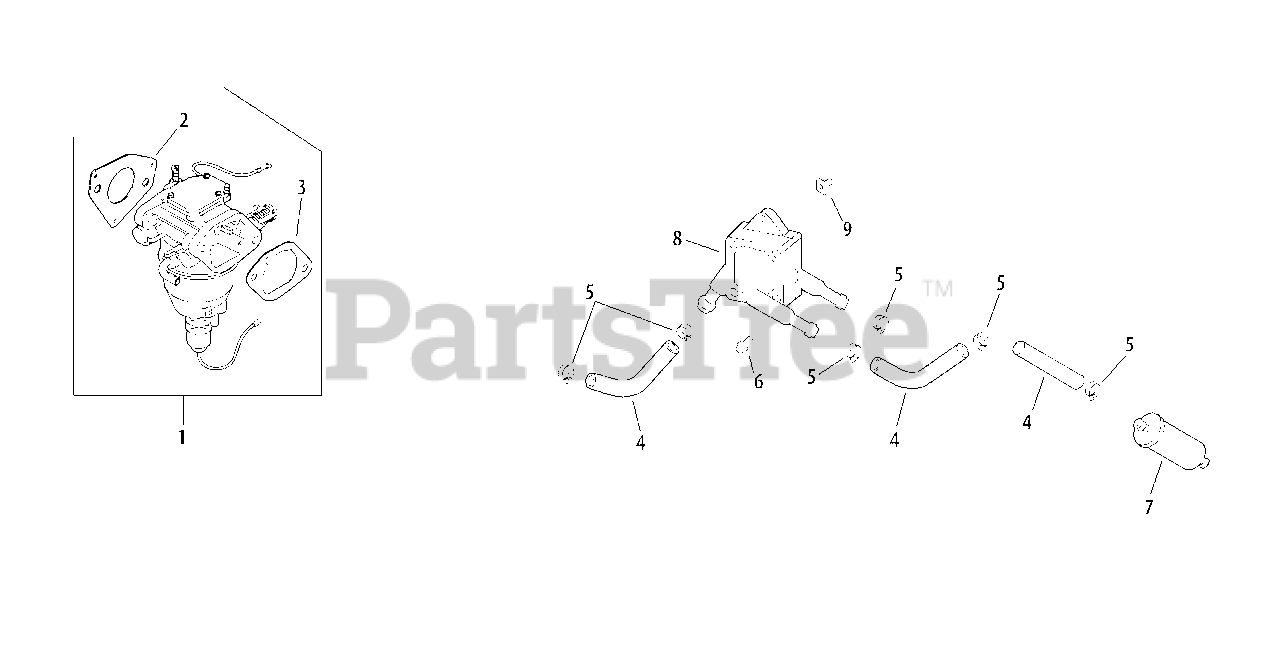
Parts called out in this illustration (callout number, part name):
1	Kit Carburetor
2	Carburetor Gasket
3	Air Cleaner Base Gasket
4	Fuel Line, 24"
5	Hose Clamp, 1/2
6	Tap Screw, M6 x 1.7 x 18
7	Fuel Filter
9	Plastic Nut (Black)
